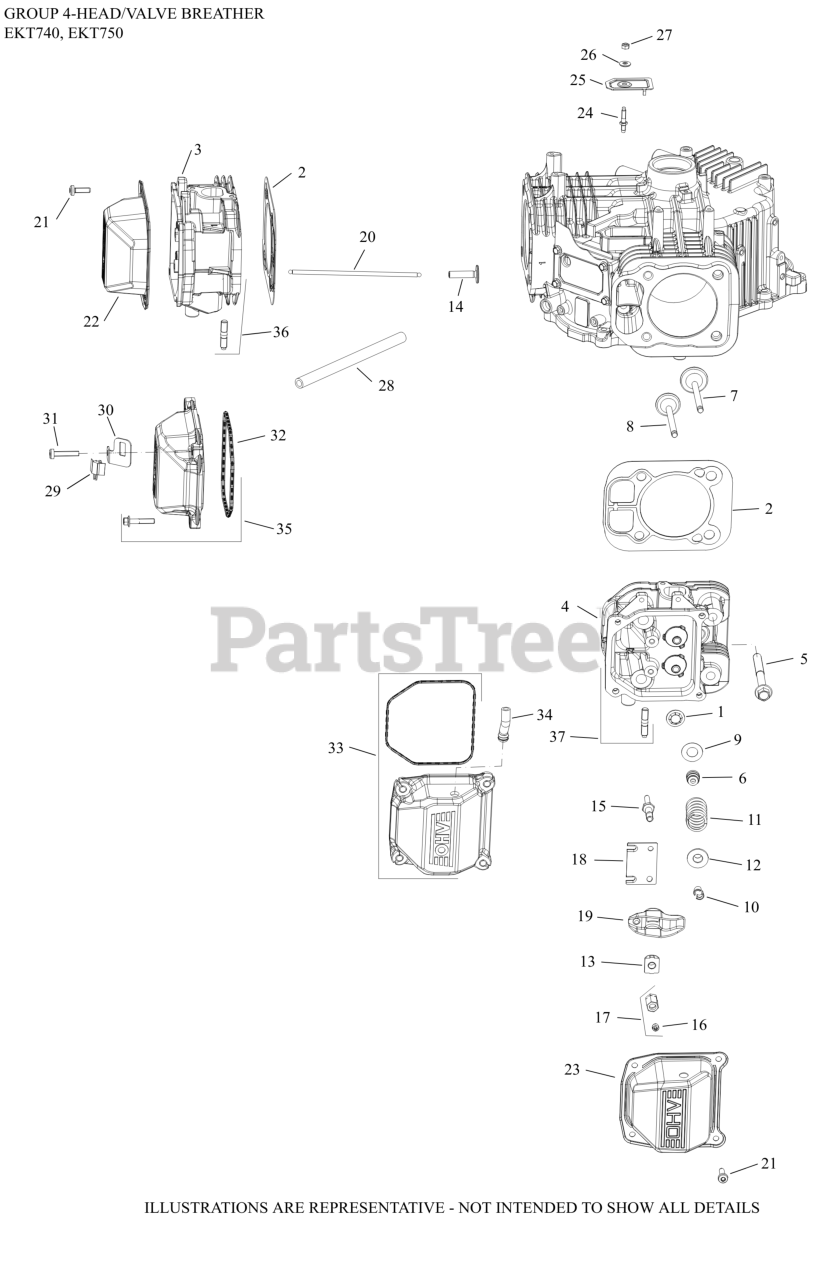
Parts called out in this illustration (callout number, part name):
1	RETAINER, VALVE GUIDE (KM)
2	KIT, CYLINDER HEAD GASKET
3	HEAD, ASSY CYL (#1)-USE 32 755 29-S
4	HEAD, ASSY CYL (#2)-(#3275530S)
5	SCREW, FLG M10X1.5X90
6	SEAL, VALVE BAND
7	VALVE, INTAKE
7	VALVE, INTAKE (.25) - (#2401702S)
8	VALVE, EXHAUST
8	VALVE, EXHAUST (.25)
9	SPACER (.010")
10	KIT, RETAINER
11	SPRING VALVE
12	CAP, VALVE SPRING
13	PIVOT, ROCKER ARM
15	STUD, ROCKER
16	SCREW, SET
17	HEX NUT ASSEMBLY
18	PLATE, GUIDE
19	ARM, ROCKER
20	ROD, PUSH
25	COVER, BREATHER REED
26	WASHER, SEALING
27	NUT, LOCK M5X.8
28	HOSE, BREATHER
29	CLIP, O2 SENSOR
30	BRACKET, OXYGEN SENSOR
31	SCREW, PAN HEAD
32	O-RING (YELLOW), VALVE CO
33	KIT,BREATHER VALVE COVER (PLASTIC)
34	HOSE, FP-USE 32 326 07-S(PLASTIC COVERS)
35	KIT, VALVE COVER-PLAIN (PLASTIC)
